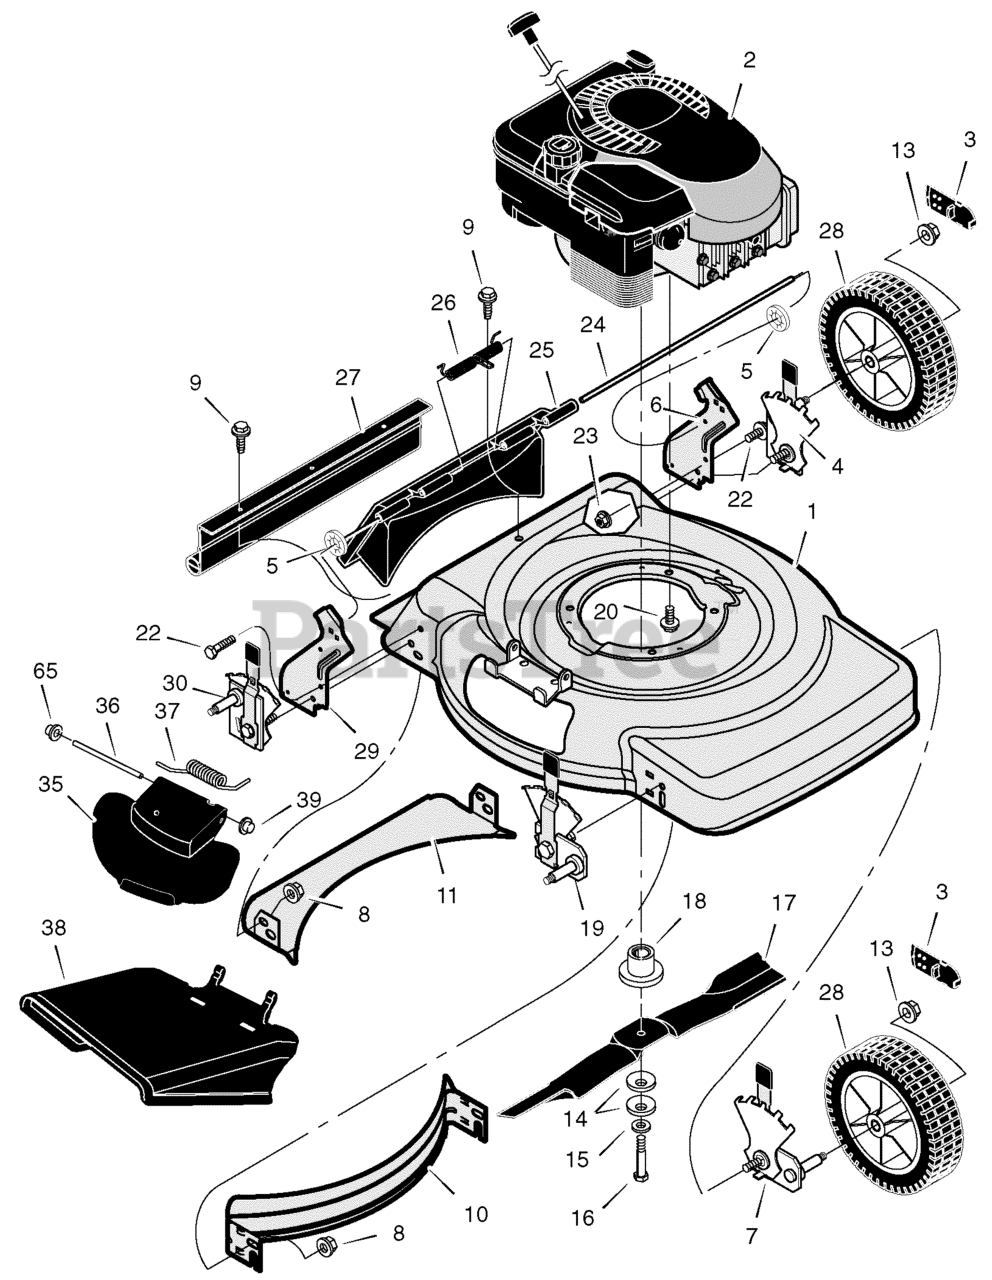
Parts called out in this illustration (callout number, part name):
1	Housing
2	Engine
3	Cap, Hub (Optional)
4	Adjuster, Left Rear Height
5	Push Retainer
6	Bracket, Left Handle
7	Bracket, Left Handle
8	Nut, Flange
9	Screw *
10	Baffle, Front
11	Baffle, Rear
13	Nut, Flange
14	Washer, Belleville
15	Washer
18	Adapter, Blade
19	Adjuster, Right Front Height
20	Bolt, Engine
22	Bolt
23	Nut, Flange
24	Rod, Pivot
25	Door, Rear (Black) *
26	Spring
27	Guard, Rear *
28	Wheel & Tire
29	Bracket, Right Handle
30	Adjuster, Right Rear Height
35	Cover, Mulch (Black)
36	Rod, Pivot *
37	Spring, Torsion *
38	Deflector, Chute (Black) *
39	Push On Cap *
